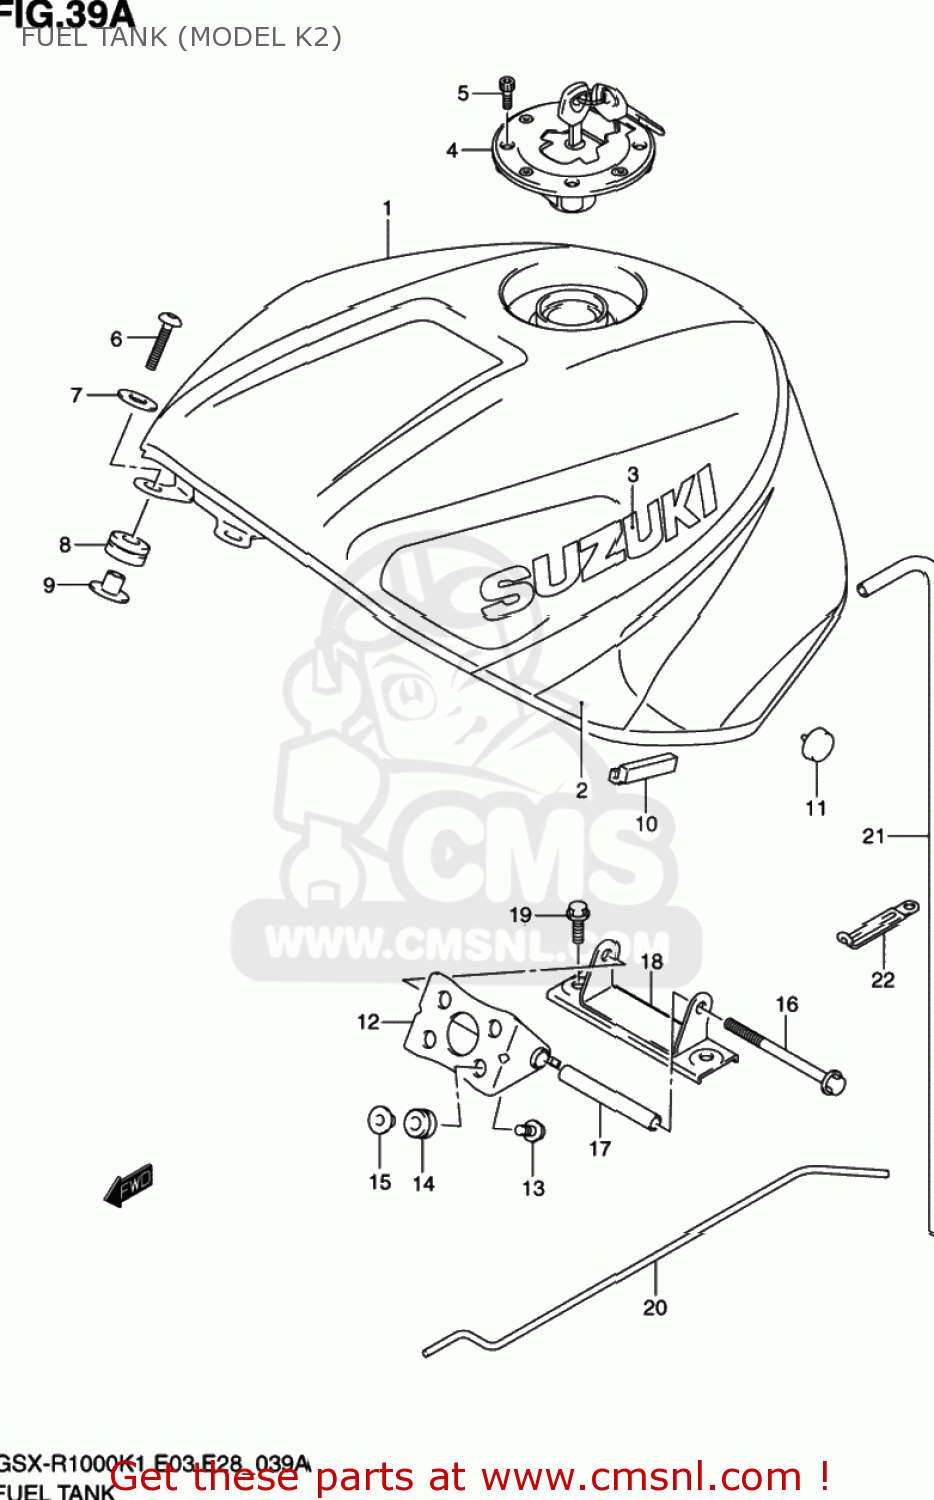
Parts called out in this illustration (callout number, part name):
1	TANK ASSY,FUEL
2	TAPE SET,FUEL TANK
3	EMBLEM,FUEL TANK
4	CAP SET,FUEL TANK
5	BOLT(5X20)
6	SCREW(6X25)
7	WASHER(6.5X22X1.6)
8	CUSHION,FUEL TANK FR
9	SPACER,FUEL TANK FR
10	CUSHION,FUEL TANK SIDE
11	CUSHION,FUEL TANK SIDE NO.2
12	BRACKET,FUEL TANK NO.1
13	BOLT(6X20)
14	CUSHION
15	WASHER
16	BOLT
17	SPACER,FUEL TANK RR
18	BRACKET,FUEL TANK NO.2
19	BOLT
20	STAY,FUEL TANK
21	HOSE,FUEL TANK WATER DRAIN
22	CLAMP(L:65)
